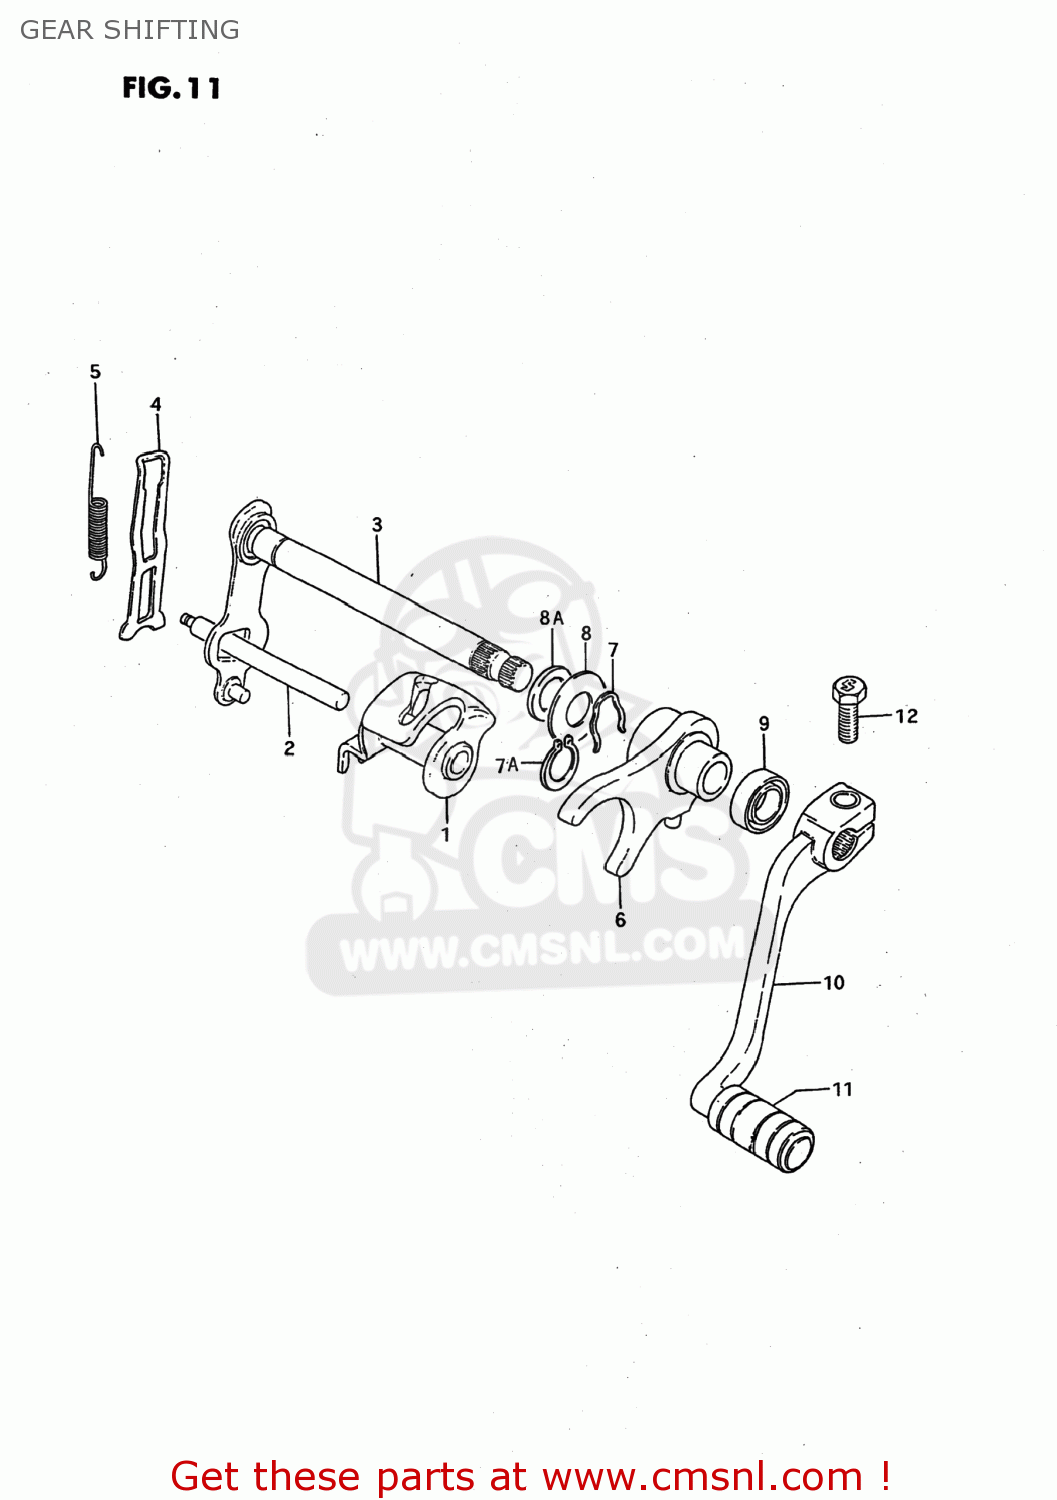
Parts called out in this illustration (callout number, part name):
1	CAM,GEAR SHIFT
2	SHAFT,GEAR SHIFT CAM
3	SHAFT,GEAR SHIFT
4	ARM,GEAR SHIFT CAM STOPPER
5	SPRING
6	FORK,GEAR SHIFT NO.1
7	SPRING,RETAINER
7A	CIRCLIP,12 MM
8	WASHER
8A	WASHER
9	OIL SEAL
10	LEVER ASSY,GEAR SHIFT
11	RUBBER,GEAR SHIFT PEDAL
12	BOLT
